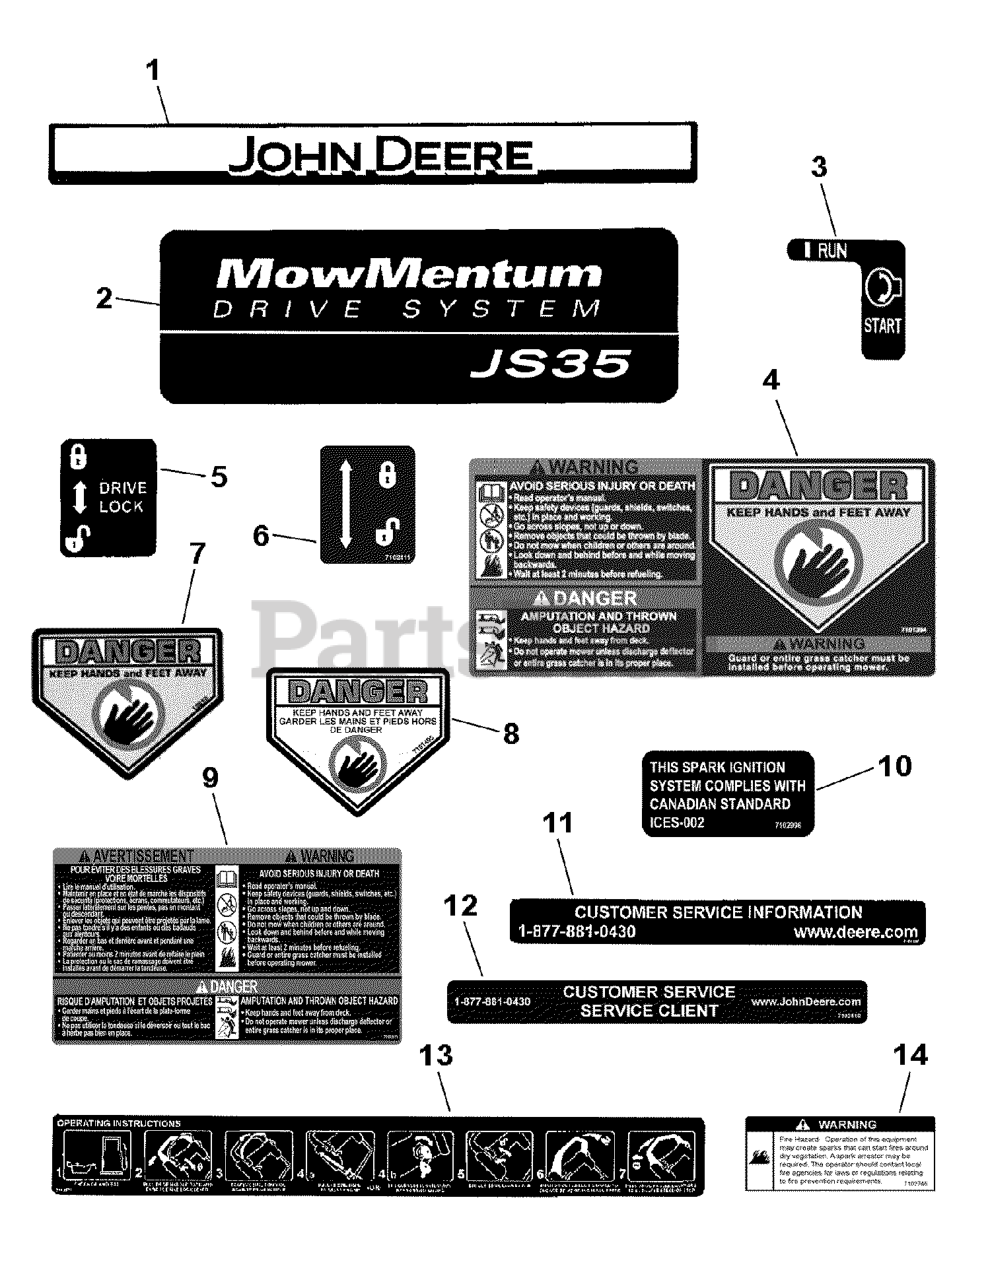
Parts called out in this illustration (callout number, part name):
1	DECAL, FRONT, JS25/35
2	DECAL, MOWMENTUM, JS35
3	DECAL, IGNITION SWITCH
4	DECAL, WARNING, REAR DISCHARGE DOOR
5	DECAL, NEUTRAL LOCK
6	DECAL, NEUTRAL LOCK, FC
7	DECAL, DANGER, CUT FINGER
8	DECAL, CPSC, FRENCH/ENGLISH
9	DECAL, FRENCH/ENGLISH, WB SAFETY
10	DECAL, COMPLIANCE, ICES
11	DECAL, CUSTOMER SERVICE, MY08, DEERE
12	DECAL, CUSTOMER SERVICE, DEERE, FRENCH
13	DECAL, OPERATION, JD
14	DECAL, ARRESTOR, SPARK
